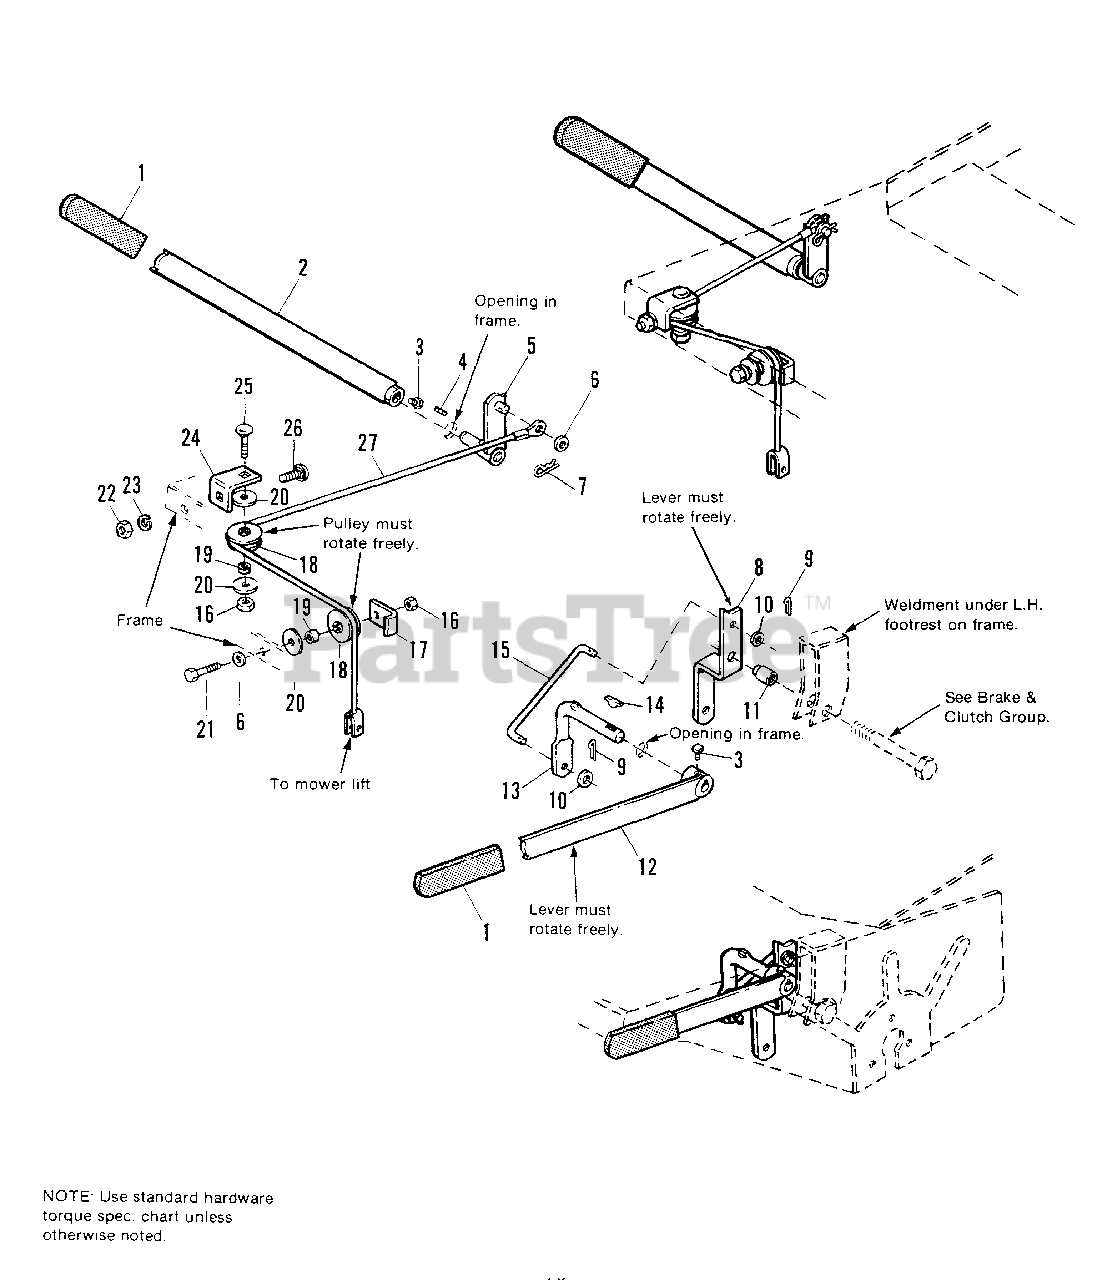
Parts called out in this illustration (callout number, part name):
1	GRIP
2	LEVER ASSY., Lift
3	SET SCREW, 1/4-20 x 3/8
4	KEY, 3/16 x 5/8
5	LEVER ASSY.
6	WASHER, 1/4
7	PIN, Quick
8	LEVER, PTO
9	PIN, Cotter, 3/4
10	WASHER, 5/16
12	LEVER ASSY., PTO
13	LEVER, PTO
14	KEY, Hi-Pro, 5/32 x 5/8
16	NUT, Hex, Lock, 1/4-20
17	GUIDE, Cable
18	PULLEY, Lift Cable
19	SPACER
20	WASHER, 1/4
21	CAPSCREW, 1/4-20 x 1.0
22	NUT, Hex, 5/16-18
23	LOCKWASHER, 5/16
24	BRACKET, Pulley
25	CARRIAGE BOLT, 1/4-20 x 1-1/4
26	CARRIAGE BOLT, 5/16-18 x 3/4
27	CABLE ASSY., Lift
